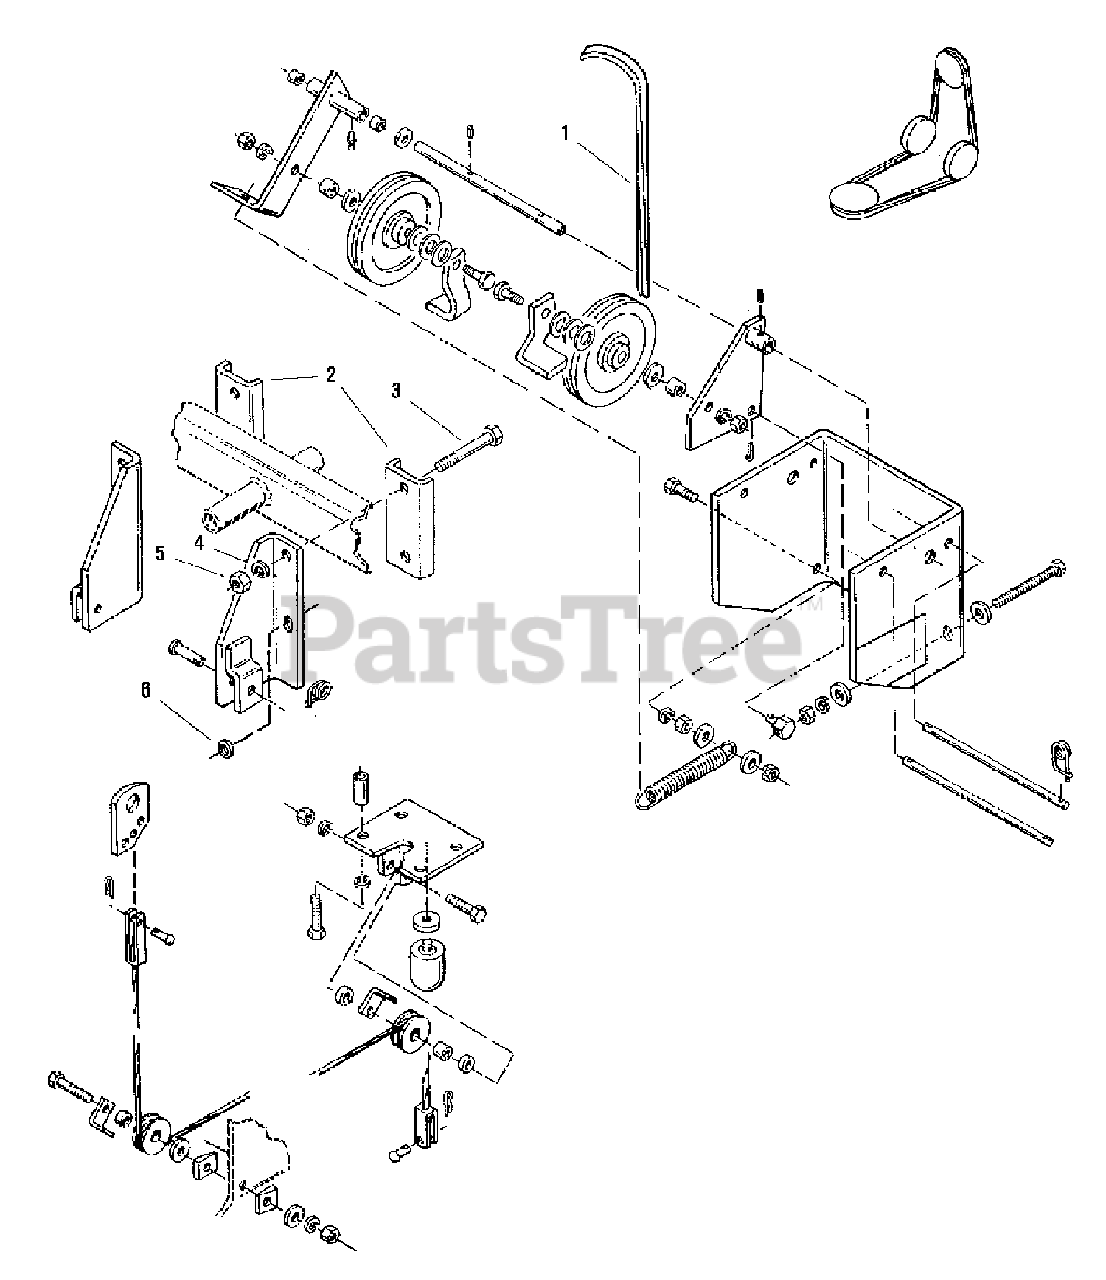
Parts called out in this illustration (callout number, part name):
1	BELT, V
2	BRACKET, Hitch
3	Capscrew, 1/2-13 x 5
4	LOCKWASHER, 1/2
5	NUT, Hex, 1/2-13
6	WASHER
7	INSTRUCTIONS, Install
